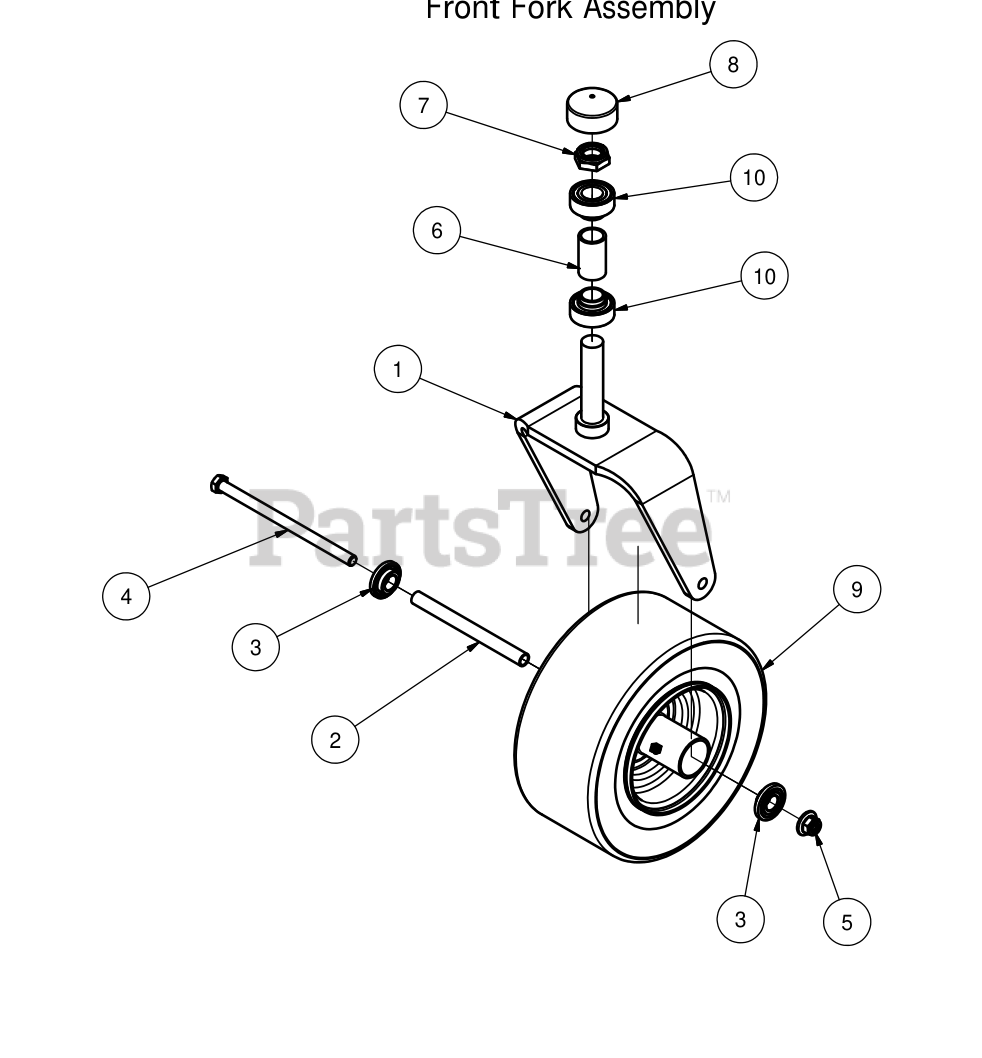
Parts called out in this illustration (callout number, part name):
1	Front Fork
2	Front Wheel Spanner
3	1 3/8" Wheel Bearing
4	1/2" x 9" GR 5 Hex Bolt
5	1/2-13 Nylon Flange Nut
6	Caster Bearing Spacer
7	1" Fine Thread 1/2 Nylock Nut
8	Rubber Bearing Cap
9	Tire and black wheel assembly
10	Caster Bearing 2009 & Up
